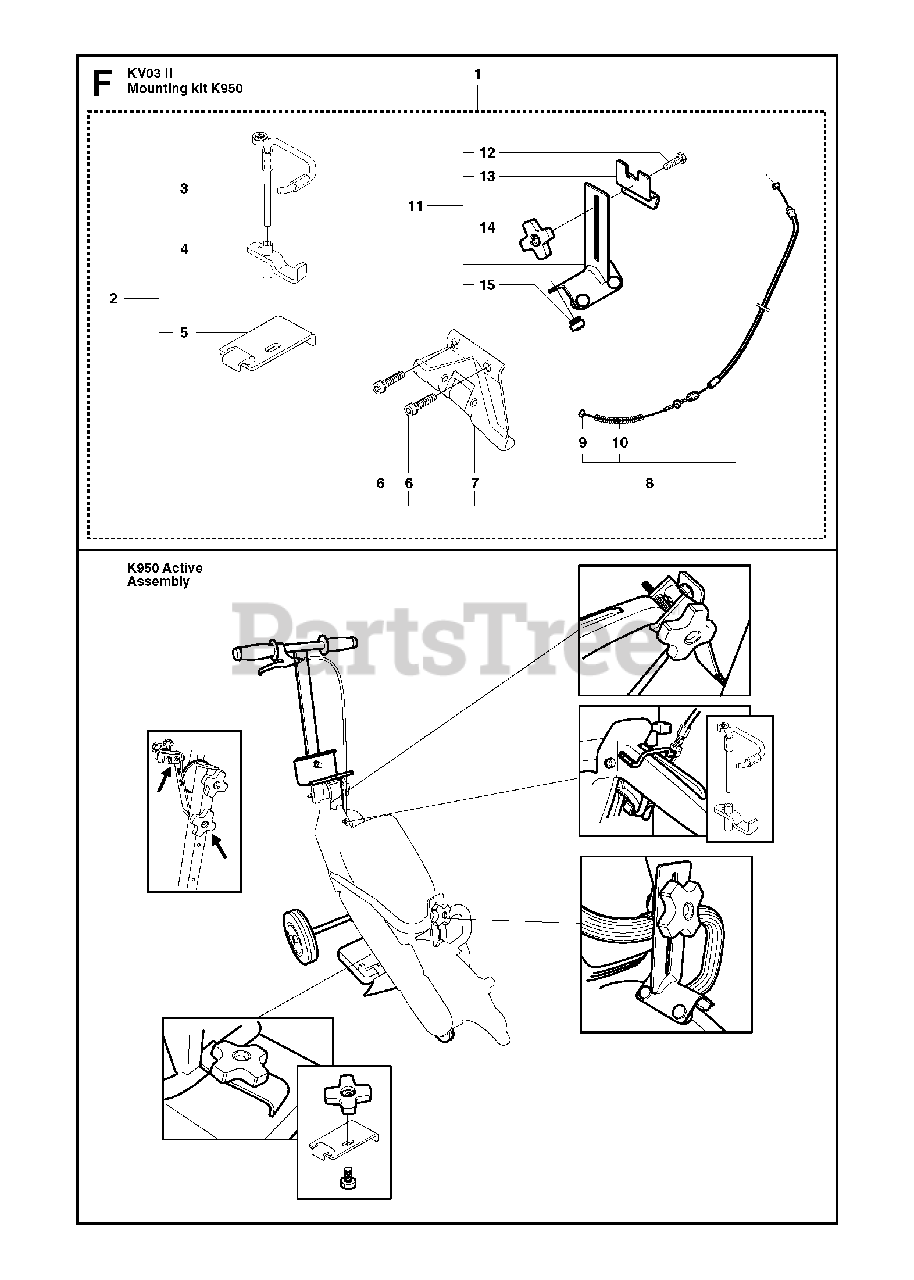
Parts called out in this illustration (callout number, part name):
1	ASSEMBLY KITIncl. 2, 11
2	CUTTING TROLLEYIncl. 3 - 8
7	GROUND SUPPORT"12"" Tools is needed (not included)"
8	THROTTLE WIREIncl. 9, 10
11	RETAINERIncl. 12 - 15
14	STEERING WHEEL
